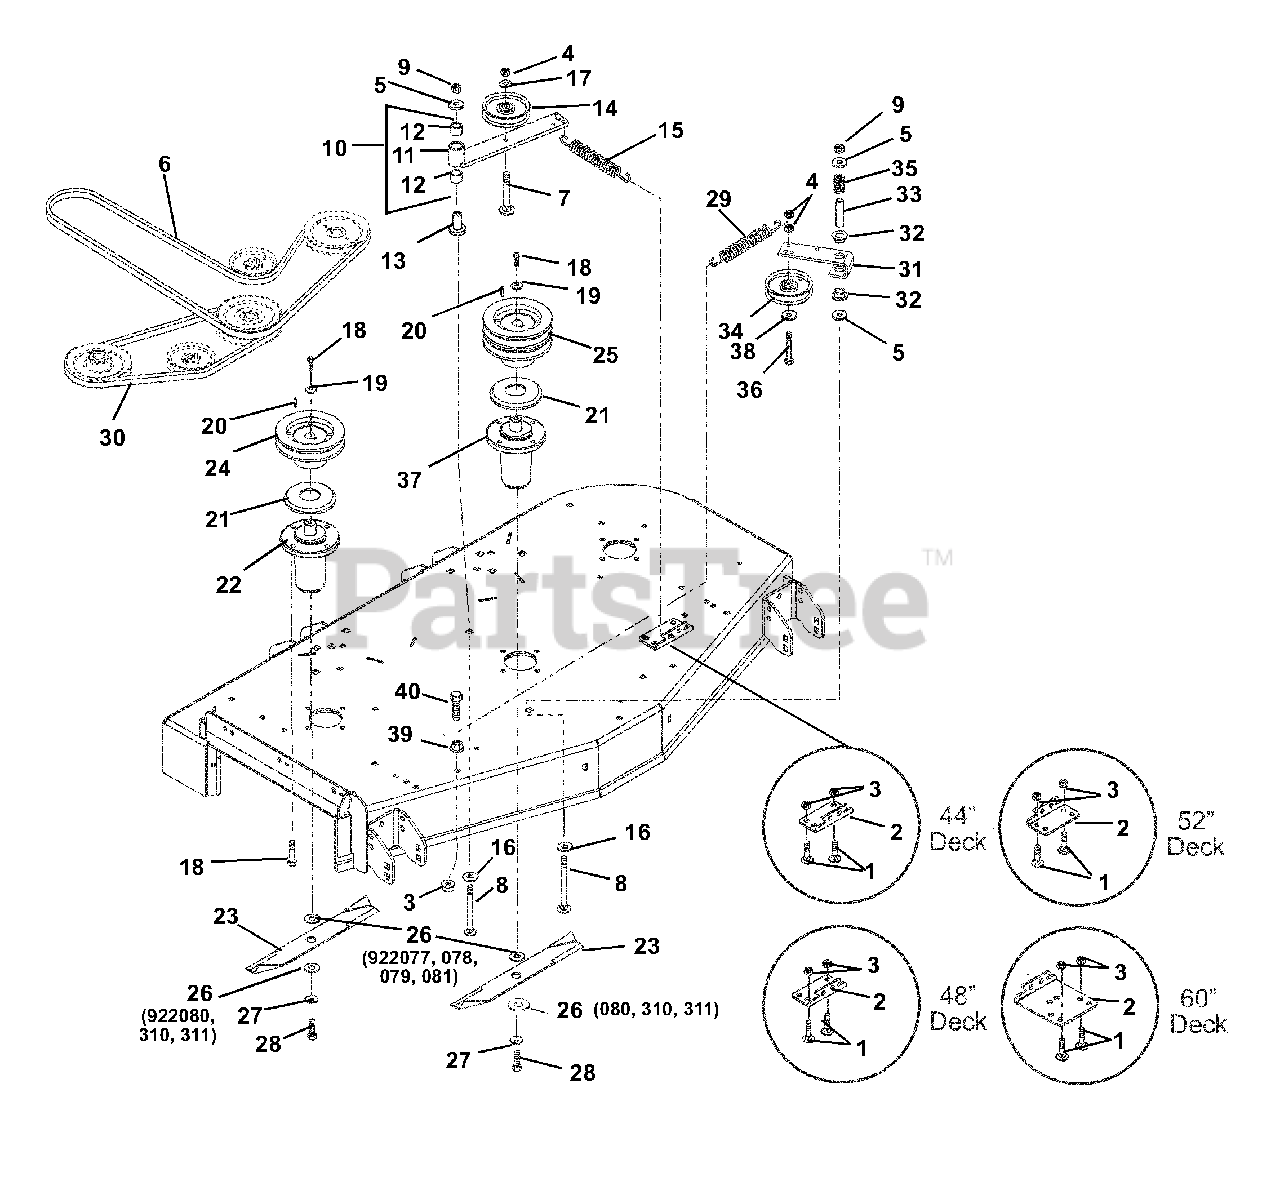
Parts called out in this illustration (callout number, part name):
1	Bolt, Round Head Square Neck .38-16 x .75 Grade 5 (077, 078, 079, 081, 310, 311)
2	Bracket, Spring (064, 077, 078, 079, 081, 083, 310, 311)
2	Bracket, Spring (080, 082)
3	Nut, Locking Top Flange .38-16
4	Nut, Locking Center .38-16
5	Washer, Flat Steel .531 x 1.25 x .10
6	V-Belt, B-Section 51.50 x .625 (064, 077, 079, 081, 083, 310)
6	V-Belt, B-Section 55.75 x .625 (080, 082)
6	V-Belt, B-Section 48.80 x .625 (078, 311)
7	Bolt-Round Head Square Neck .38-16 x 2.75 Grade 5
8	Bolt, Round Head Square Neck .50-13 x 3.50 Grade 5
9	Nut, Locking Top Flange .50-13
10	Assembly, Idler Pivot Arm
11	Weldment, Idler Pivot Arm
12	Bearing, 1.00 x 1.12 x .75
13	Bearing, Pedestal Powdered Metal
14	Idler, Flat 4.00 x .38 (2.00 W)
15	Spring, Extension
16	Washer, Flat Steel .755 x 1.375 x .062 (064, 077, 078, 079, 081, 082, 083, 310, 311)
17	Washer, Flat Steel .375 x 1.125 x .065
18	Bolt, Hex .38-16 x 1.00 Grade 8
19	Washer, Cupped Serrated .375
20	Key, Square .25 x .25 x 1.00 RC 40-50
21	Slinger, Dust
22	Assembly, Maintenance Free Spindle
23	Blade, Mower (18.00) (079, 081)
23	Blade, Mulching (18.00) (079, 081)
23	Blade, Mower 60" (080, 082)
23	Blade, Mower 60" Tungsten Mulch (080, 082)
23	Blade, Mower (064, 077, 078, 083)
23	Blade, 32" (16.25) (310, 311)
23	Blade, Mulching (064, 077, 078, 083)
24	Weldment, Spindle Sheave 5.00 (064, 077, 078, 079, 081, 083, 310, 311)
24	Weldment, Spindle Sheave 6.00 (080, 082)
25	Sheave, Double (5.25") (064, 077, 078, 079, 081, 083, 310, 311)
25	Sheave, Double (6.25") (080, 082)
26	Washer, Flat .64 x 1.81 x .250
27	Washer, Bellville .63 x 1.625 x .14
28	Bolt, Hex .62-18 x 1.75 Grade 8
29	Spring, Extension
30	V-Belt, B-Section 19.10 x .672 (079, 081)
30	V-Belt, B-Section 23.94 x .625 (080, 082)
30	V-Belt, 5L-Section 49.97 x .672 (064, 077, 078, 079, 081, 083, 310, 311)
31	Arm, Idler Pivot
32	Bushing, Flange .762 x 1.00 x .58 x 1.48 Nylon
33	Spacer .56 x .75 x 2.44 Steel
34	V-Idler, 4.00 x .38
35	Spring, Compression .085 x .80 x 1.00
36	Bolt, Hex .38-16 x 2.25 Grade 5
37	Spindle Assembly (Center)
38	Washer, Flat Steel .406 x .812 x .065
39	Nut-Flange .375-16
40	Bolt-Hex .38-16 x 3.50 Grade 5
